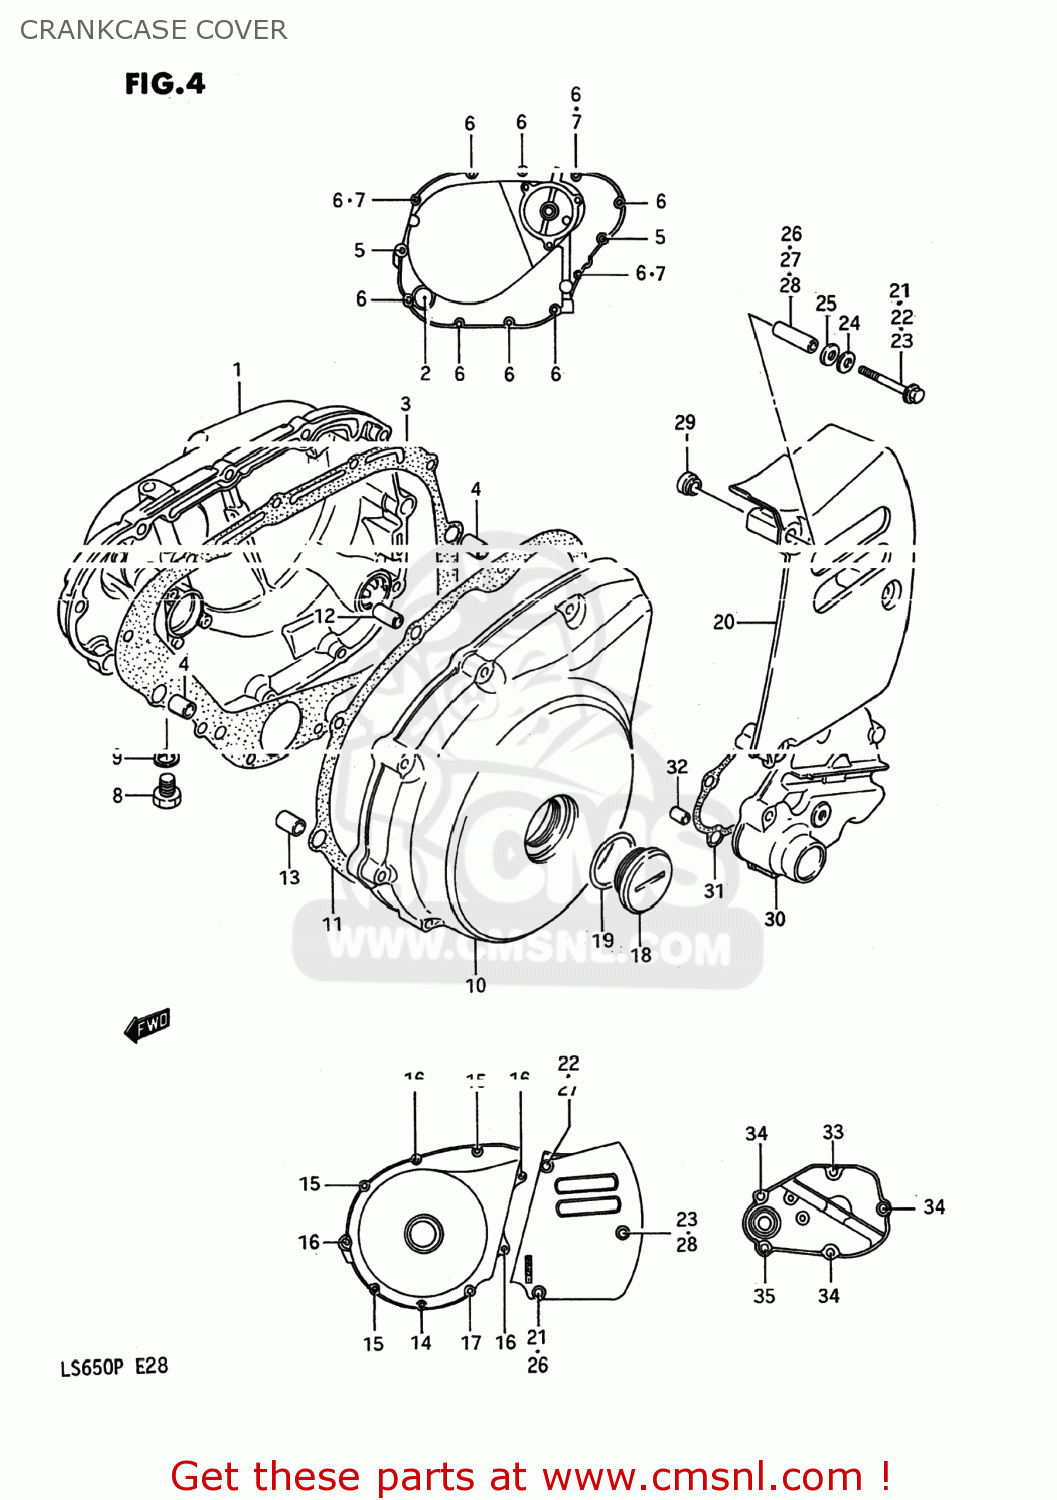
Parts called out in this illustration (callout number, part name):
1	COVER,CLUTCH
2	LENS,OIL LEVEL CHECK
3	GASKET,CLUTCH COVER (NAS)
4	PIN
5	BOLT
6	BOLT
7	GASKET(5.8X13X1.2) (NAS)
8	PLUG
9	GASKET(12.1X16.2X3.7) (NAS)
10	COVER,GENERATOR
11	GASKET,GENERATOR COVER (NAS)
12	PIN
13	PIN
14	BOLT
15	BOLT
16	BOLT
17	BOLT
18	PLUG,36X10
19	O RING(D:3.1,ID:32.7)
20	COVER,ENGINE SPROCKET
21	BOLT
22	BOLT
23	BOLT
24	WASHER
25	WASHER(8.7X15X2.1)
26	SPACER (6.1X9X31.5)
27	SPACER (6.1X9X38.3)
28	SPACER (6.1X9X41.3)
29	WASHER(8.7X16X5)
30	COVER,GEAR SHIFT
31	GASKET,GEAR SHIFT COVER (NAS)
32	PIN
33	BOLT
34	BOLT
35	BOLT
